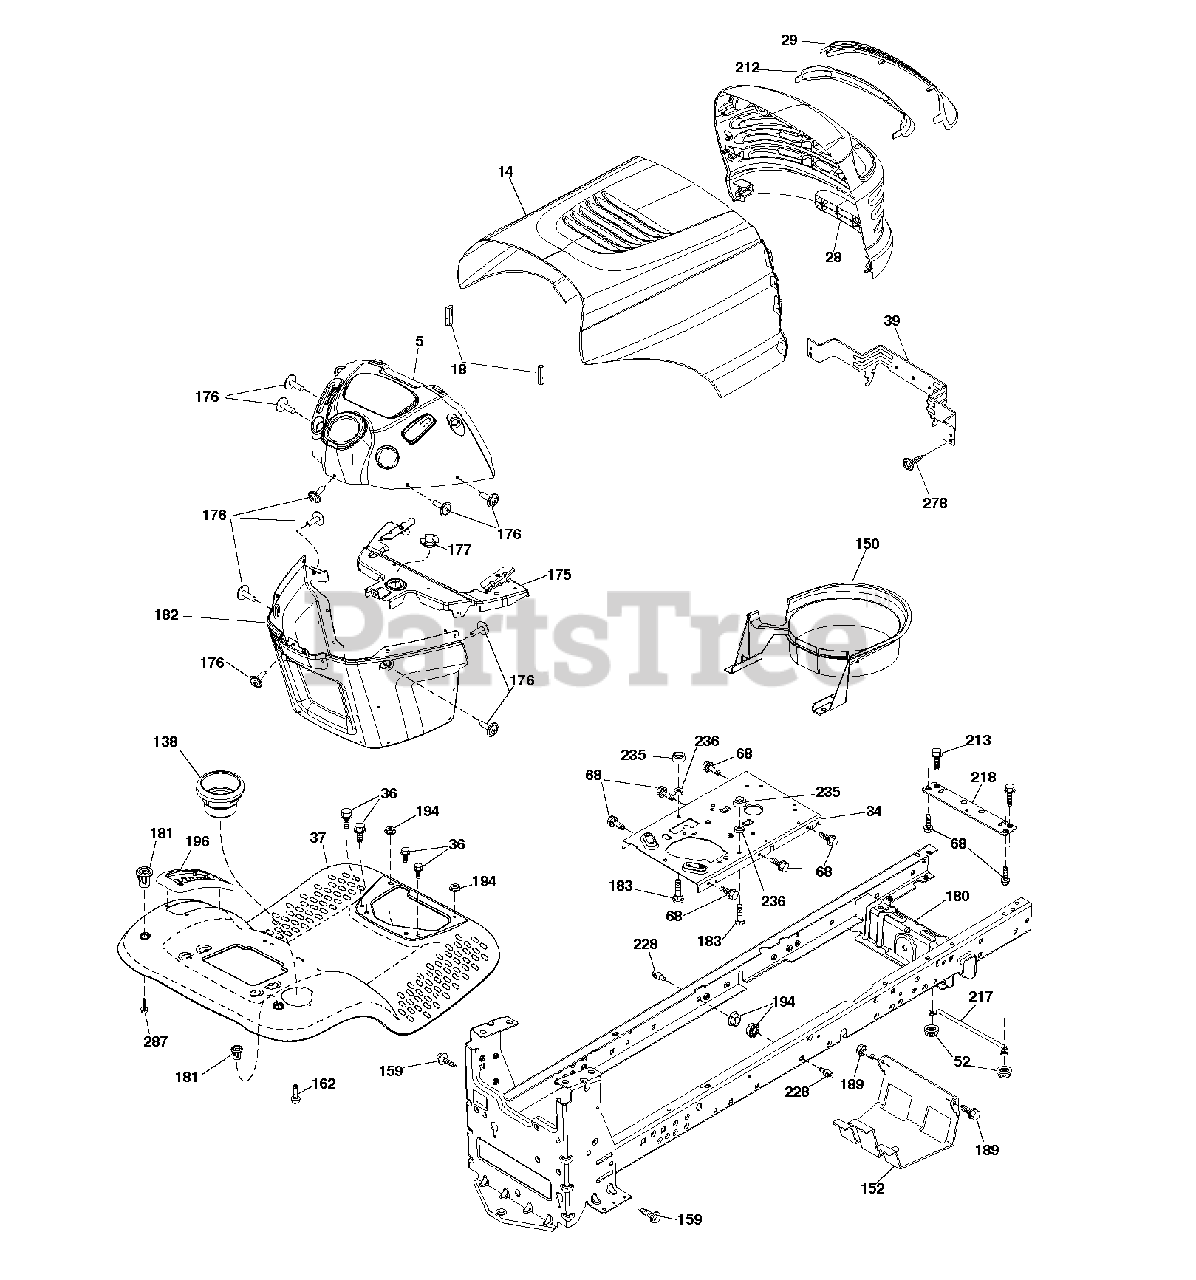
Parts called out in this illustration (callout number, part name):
5	DASH.P/L.TEX.CBL.CL.N/CHK.BLAC
18	BUMPER.HOOD.LARGE.1.75"
29	LENS.LASER LT.CLEAR.BAR
34	PLATE.ENGINE.WELDED.CHASSIS
36	SCREW 5/16"
37	FENDER.TLT.FS.W/CPH.550
39	BRACKET PIVOT
52	LOCKNUT
68	SCREW LT
138	CUPHOLDER.TL.TEX.BLACK
150	DUCT.INTAKE.AIR.KAW
152	SHIELD.BROWNING.W/TEX
159	SCREW, 3/8-16X3/4
162	SCREW.HI-LO.CONSOLE
175	CROSSMEMBER.LT
176	SCREW.#10-24X5/8.RN.QU
177	BUSHING STEERING
180	CHASSIS
181	FEND/FTRST.PCH.CPH.NFW
182	DASH.LOWER.LT.CCS
183	BOLT.5/16-18X1-1/4 FULL THD
189	SCREW
194	NUT LOCK HEX FLANGE 5/16-18
213	BOLT
217	ROD.PIVOT.HOOD
218	X-PIECE.HOOD.STOP.NON/
228	STUD.FASTNER.W/ANTI-ROTATE
235	SPACER FENDER
236	NUT.CENTERLOCK.5/16-
278	SCREW.#10 X 0.750.BOS (2 2)
287	SCREW 1/4X20
